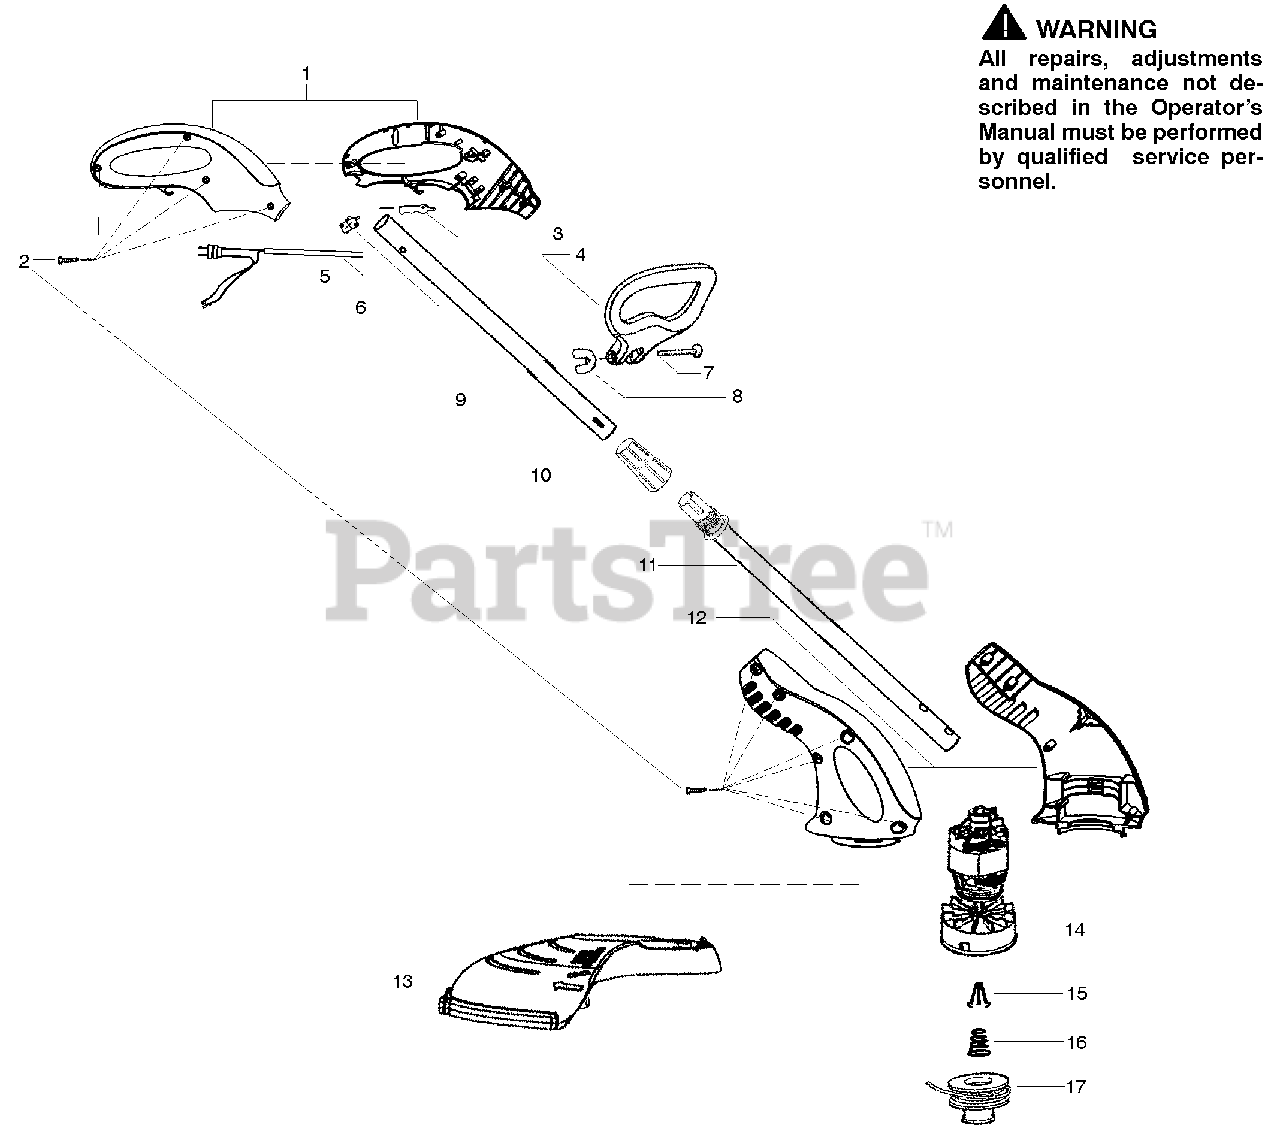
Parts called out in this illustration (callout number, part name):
1	Assy-Handle Set
2	Screw (10pcs.)
4	Assy-Handle Assist
5	Assy-Wiring Harness
7	Bolt-Carriage
8	Wingnut
9	Assy-Upper Tube
10	Nut-Collett
11	Assy-Lower Tube
12	Housing Set
13	Assy-Shield
14	Assy-Motor/Hub
15	Retainer-Spool
16	Spring-Return
17	Accy-Spool w/Line
